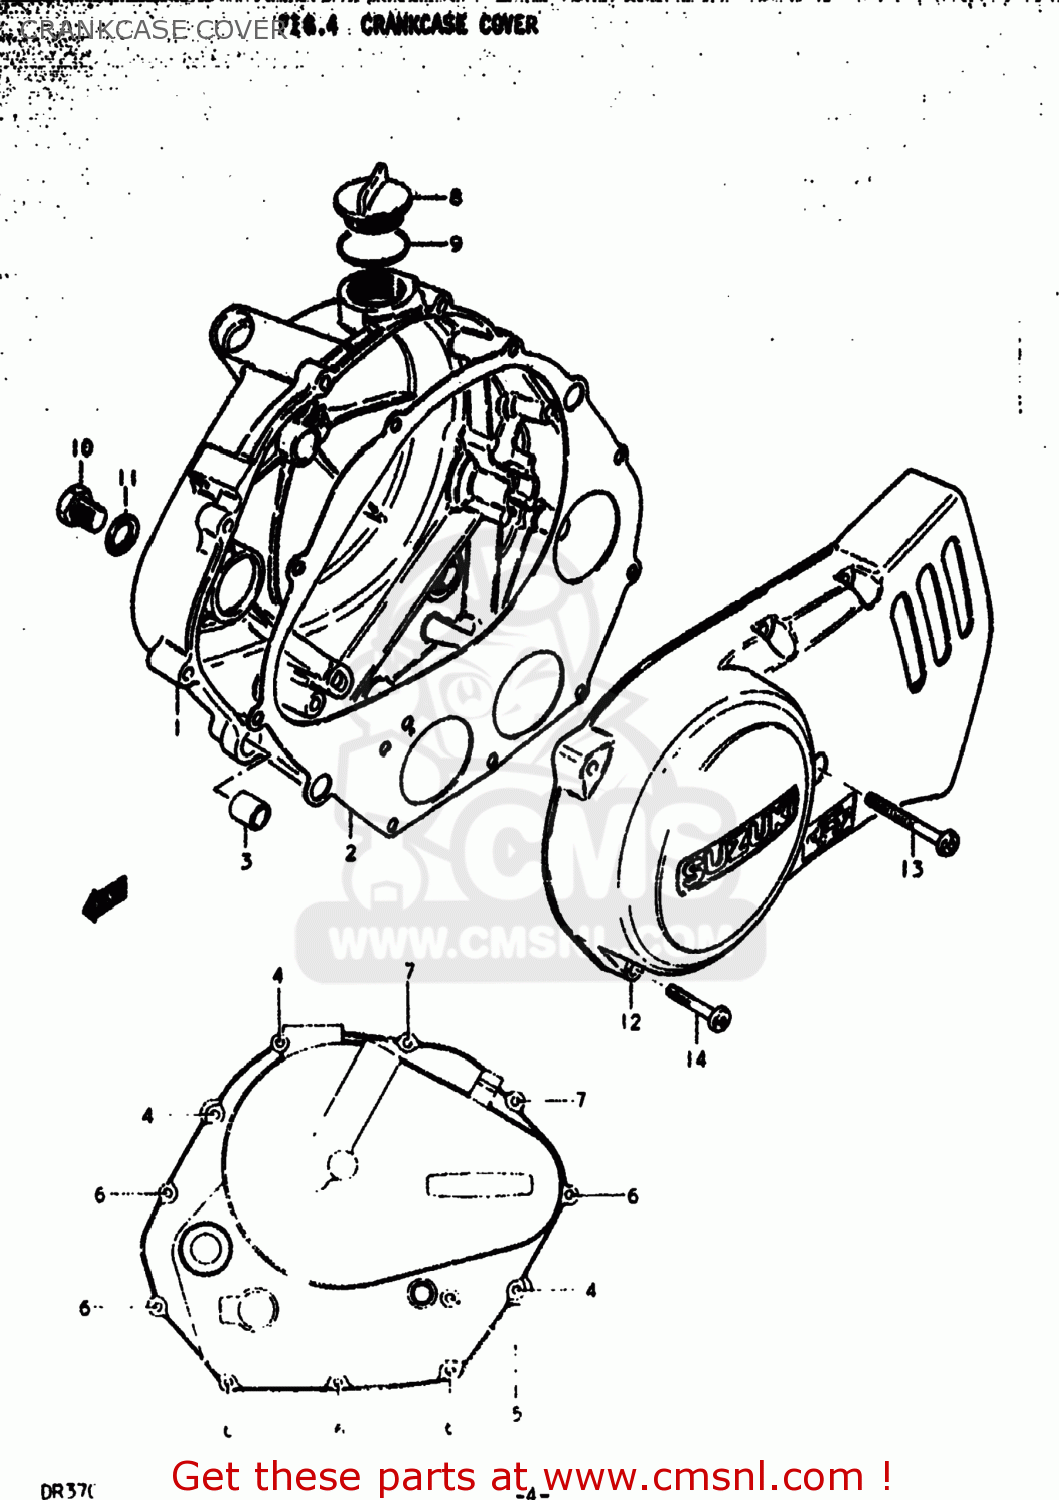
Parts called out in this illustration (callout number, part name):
1	COVER,CLUTCH
2	GASKET,CLUTCH COVER (MCA)
3	PIN
4	SCREW
5	SCREW
6	SCREW (6X35)
7	SCREW
8	CAP
9	O RING(D:2.2,ID:32)
10	PLUG (14X12)
11	GASKET(14X19.2X2) (NAS)
12	COVER,MAGNETO
13	SCREW (6X45)
14	SCREW
